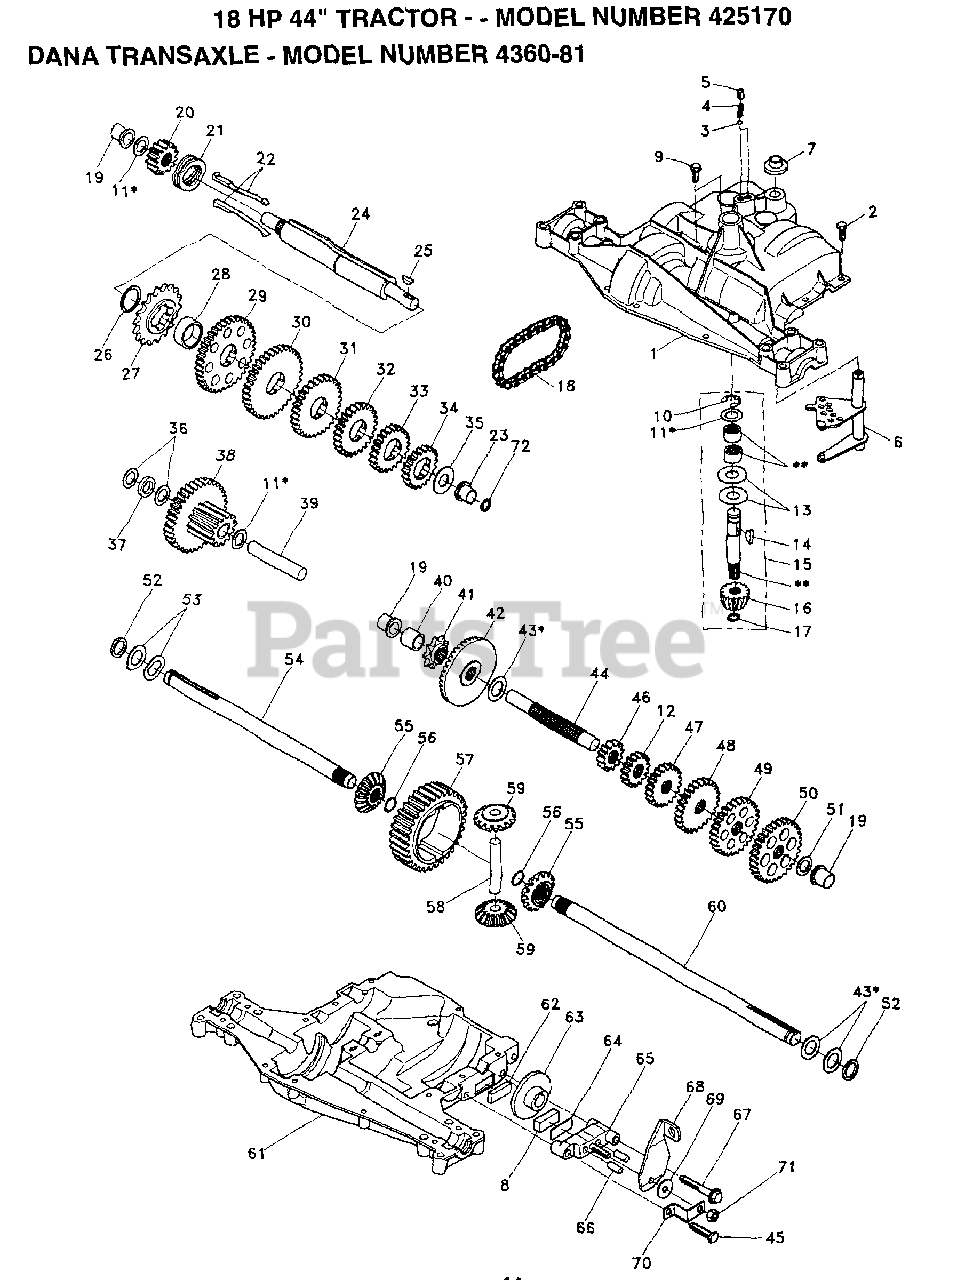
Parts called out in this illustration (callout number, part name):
1	HOUSING, UPPER
3	BALL, DETENT
4	SPRING, DETENT
5	SCREW, SET
6	KIT, SHIFTER ASSEMBLY
7	BOOT, SHIFTER
8	PUCK, FRICTION
9	SCREW TAPPING WITH SEALER
10	RING, RETAINING
11	ASSY, KIT, SHIM .625 SHAFT
12	GEAR, SPUR, 15T
13	WASHER, PLAIN .632 X 1.38 X .046
14	KEY, WOODRUFF, #9
15	ASSY KIT INPUT SHAFT
16	PINION BEVEL 14 TEETH
17	RING, RETAINING
18	CHAIN, 24 PITCHES
19	BEARING, FLANGE
20	GEAR, SPUR, 14 TEETH
21	COLLAR, CLUTCH
22	ASSY, KIT, CLUTCH KEYS
23	BEARING, FLANGE
24	SHAFT, INTERMEDIATE
25	KEY, WOODRUFF, #61
26	RING, RETAINING
27	SPROCKET, 18 TEETH
29	GEAR, SPUR, 37 TEETH
30	GEAR, SPUR, 35T
31	GEAR, SPUR, 30 TEETH
32	GEAR, SPUR, 25 TEETH
33	GEAR, SPUR, 22 TEETH
34	GEAR, SPUR, 19 TEETH
35	WASHER, PLAIN .640 X 1.37 X .061
36	WASHER, PLAIN .632 X 1.00 X .026
37	SPACER .630 X 1.00 X .169
38	ASSY GEAR COMB 12&35 TEETH
39	SHAFT, IDLER
40	SPACER .635 X .875 X .755
41	SPROCKET, 9 TEETH
42	GEAR, BEVEL, 42 TEETH
43	ASSY, KIT, SHIM .750 SHAFT
44	SHAFT, DRIVE
45	SCREW TAPPING
46	GEAR SPUR, 12 TEETH
47	GEAR, SPUR, 20 TEETH
48	GEAR, SPUR, 25 TEETH
49	GEAR, SPUR, 28 TEETH
50	GEAR, SPUR, 31 TEETH
51	WASHER, PLAIN .632 X 1.00 X .060
52	WASHER, NEOPRENE
53	WASHER, PLAIN .758 X 1.25 X .031
54	AXLE LEFT HAND
55	GEAR MITER 15 TEETH
56	RING, RETAINING
57	GEAR, SPUR, 32 TEETH
58	SHAFT, CROSS
59	GEAR, MITER, 15 TEETH
60	AXLE, R.H.
61	HOUSING, LOWER
62	PUCK, FRICTION
63	DISC, BRAKE
65	JAW, BRAKE
66	PIN, DOWEL
67	SCREW, SELF-TAPPING
68	LEVER ACTUATING
69	WASHER, PLAIN .321 X 1.00 X .055
70	BRACKET, ANTI-ROTATION
71	LOCKNUT 5/16-24
